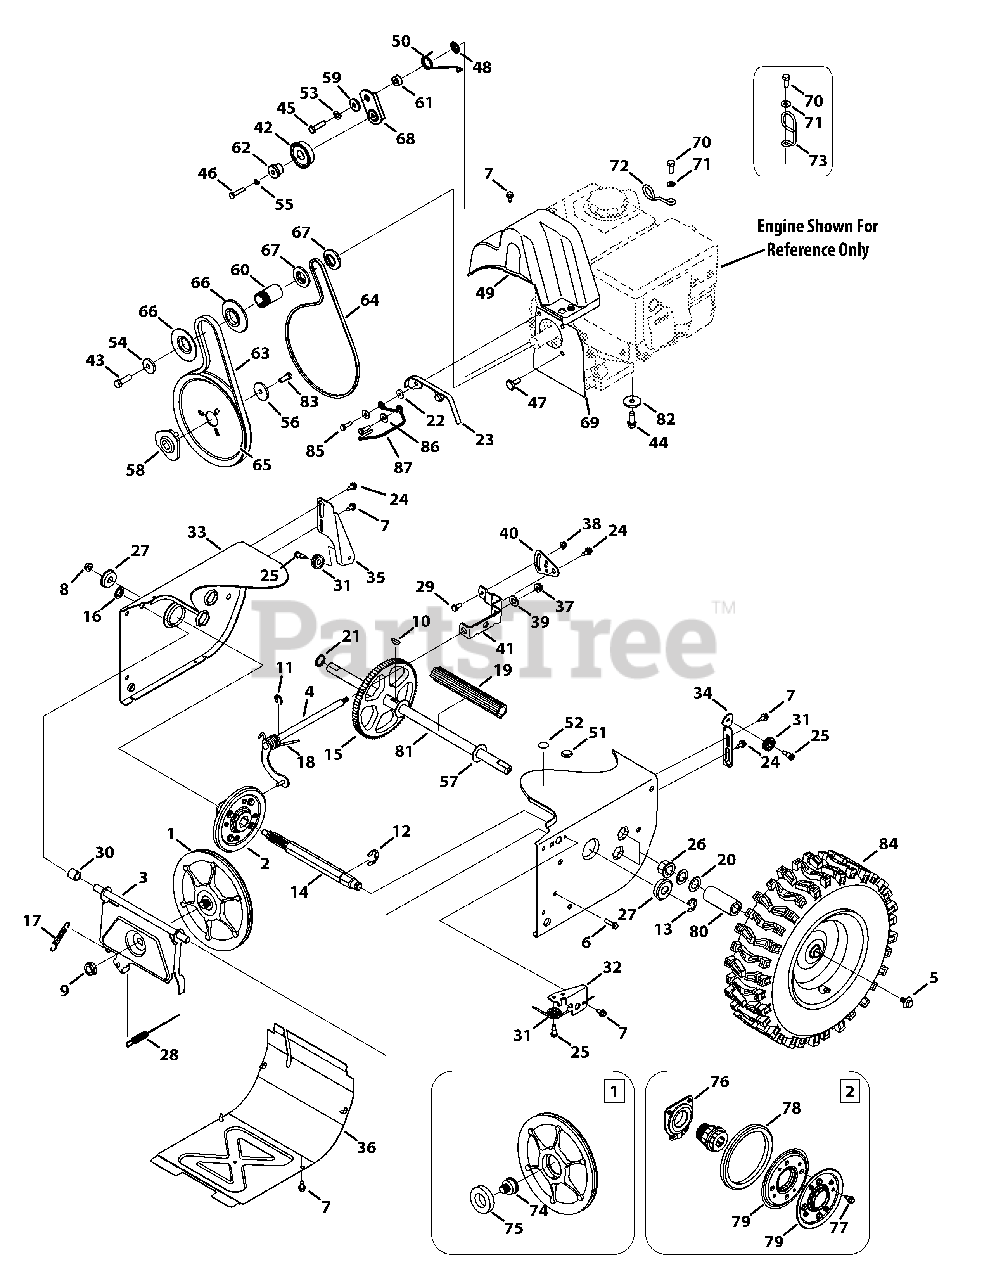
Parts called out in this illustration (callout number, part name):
1	Disc Assembly, Friction Wheel
2	Friction Wheel Assembly, 5.5 OD
3	Friction Wheel Support Bracket
4	Rod Shift Assembly
5	Screw, 5/16-24 x .750
6	Taptite Screw, 1/4-20 x 1.000
7	Taptite Screw, 1/4-20 x .625
8	Flange Lock Nut, 3/8-16
9	Flange Nut, 5/8-18
10	Hi-pro Key, 3/16 x 3/4 Dia.
12	Retaining E-Ring, .875 Dia.
13	E-Ring, .750 Dia.
14	Hex Shaft, 7-Tooth
15	Gear, 80-Tooth
16	Speed Nut, .500
17	Extension Spring
18	Torsion Spring, .750 x .968
19	Axle Spacer
20	Flat Washer, .793 x 1.24 x .060
21	Flat Washer, .75 x 1.00 x .060
22	Washer, Flat, .330 x .687 x .030
23	Belt Cover
24	Shoulder Screw, .368 x .113, 1/4-20
25	Shoulder Screw, 1/4-28, .340 x .355
26	Hex Flange Bearing
27	Ball Bearing, 17 x 40 x 12
28	Wheel Clutch Cable, 44.955"
29	Hex Head Screw, 1/4-20 x .620
30	Spacer, .508 ID x .75 OD x .68
31	Cable Roller
32	Auger Cable Front Guide Bracket
33	Frame
34	Auger Cable Guide Bracket
35	Drive Cable Guide Bracket
37	Flange Lock Nut, 5/16-18
38	Flange Lock Nut, 1/4-20
39	Washer, Flat, .469 x .875 x .105
40	Speed Selector Pivot Bracket
41	Speed Selector Shift Bracket
42	Idler Pulley Assembly
43	Hex Screw, 3/8-24 x 1.25
44	Sems Screw, 3/8-16 x 1.00
45	Hex Screw, 5/16-24 x 1.25
46	Hex Screw, 1/4-20 x 1.25
47	Shoulder Screw, 5/16-24 x .5
48	Push-on Nut, .25 Dia.
49	Belt Cover, 4-Way lrg. block
49	Belt Cover, 4-Way
50	Torsion Spring, .850 ID x .333
51	Plug, 3/8 ID
52	Plug, 1/2 ID
53	Lock Washer, 5/16
54	Flat Washer, .45 x 1.5 x .172
55	Washer, Lock, 1/4
56	Flat Washer, .34 x 1.50 x .150
57	Washer, Flat, .760 x 1.49 x .060
58	Adapter Pulley, .75 Dia.
59	Shoulder Spacer, .3175 x .5 x .0975
60	Spacer, .875 ID x 1.185 OD
61	Spacer, .340 x .750 x .330
62	Shoulder Space, .260 x .785 x .538
63	Auger Drive Belt, Standard
64	Wheel Drive Belt, Standard
65	Auger Drive Pulley, 8.1 x .5
66	Pulley Half, 2.600 OD
67	Pulley Half, 3/8 x 1.716 OD
68	Wheel Drive Idler Bracket
69	Cover Plate, Standard
70	Hex Head Screw, 1.25 x 20
71	Washer, Flat, .330 x .630 x .0635
72	Cable Guide
73	Cable Guide
74	Friction Disc Bearing Pin
75	Ball Bearing, 30 x 55 x 13
76	Bearing Assembly
77	Taptite Screw, 5/16-18 x .750
78	Friction Wheel Rubber
79	Friction Wheel Plate
80	Spacer, 1.25 x .75 x 3.0
81	Axle, .75 x 22
82	Washer, Flat, .38 x 1.38 x .125
83	Hex Head Screw, 5/16-24 x .875
84	X-Trac Wheel, 15 x 5 x 6, LH
84	X-Trac Wheel, 15 x 5 x 6, RH
85	Hex Head Screw, 5/16-24 x 1.00
86	Washer, Flat, .349 x .879
86	Belt Guide
